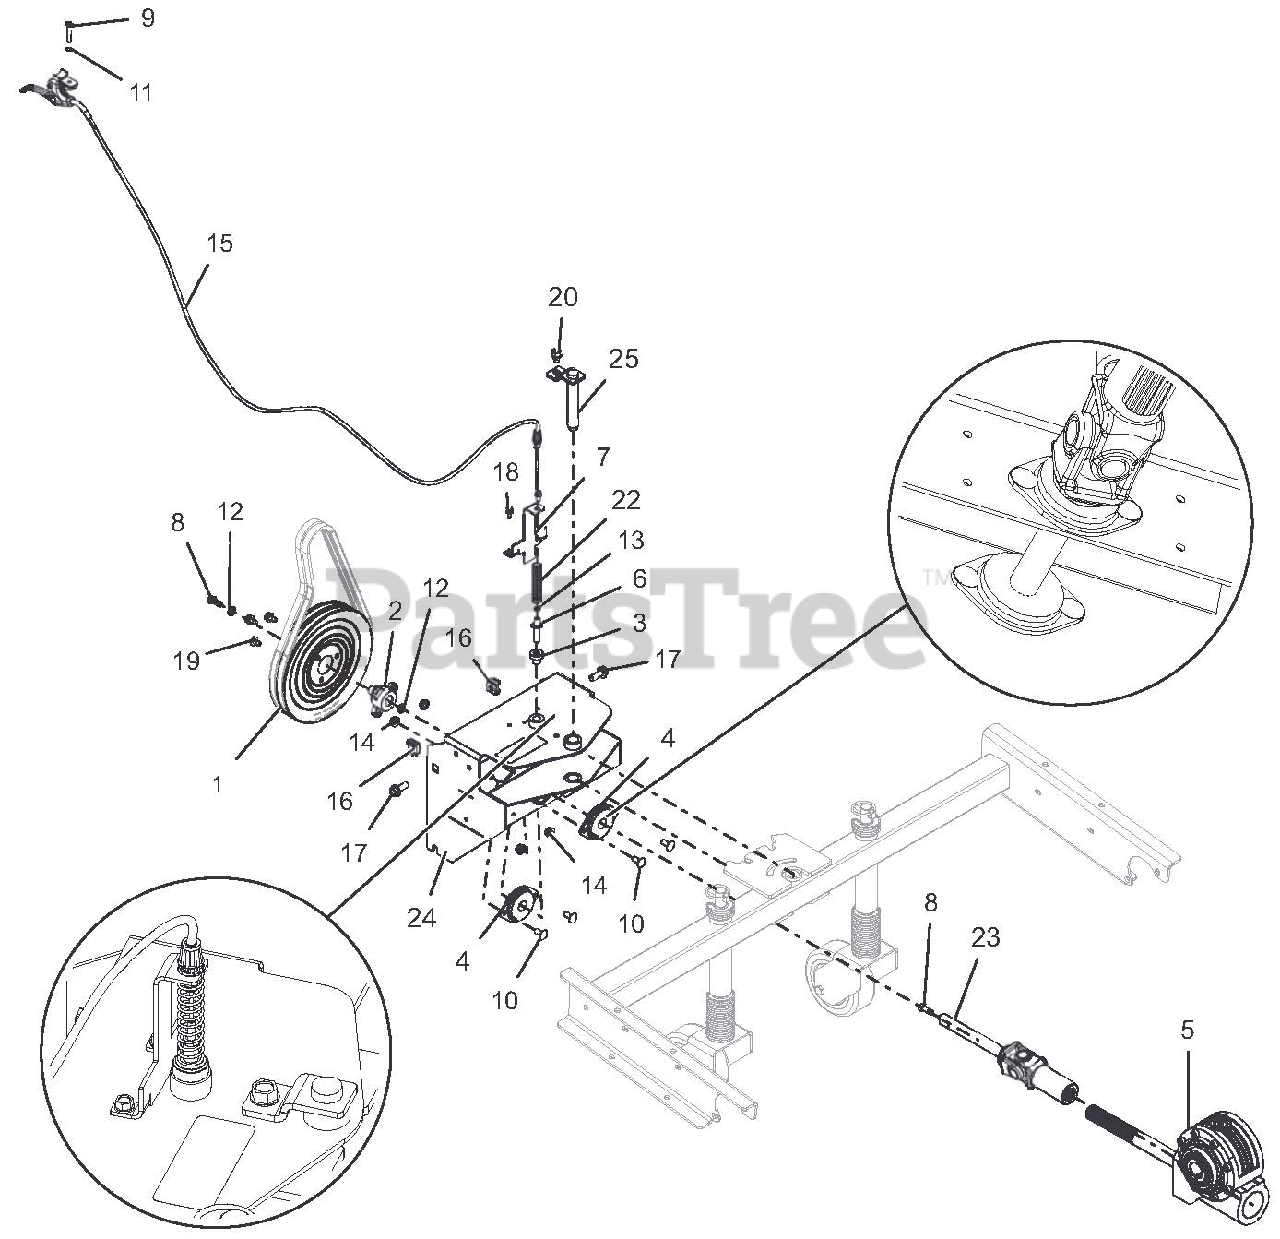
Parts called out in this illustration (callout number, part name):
1	PULLEY, DUAL GROOVE
2	HUB, ATTACHMENT PULLEY
3	SPCR, -FLANGED .390X.500X.781
4	BEARING, 2 BOLT FLANGE - .75 ID
5	GEARBOX, WORM - 8.25:1
6	PIN, ADJUSTABLE ANGLE BRUSH
7	BRKT, PIN HOLDER
8	BLT-HEX .31-24X.75 GR5 YWZC
9	SCR, -- MCH .25-20X1.50 OVAL HD
10	BLT-RDHDSQNK .31-18X.75 G5 YWZC
11	WSHR, LK-INT .250 TH TYA
12	WSHR-LK .31X.097 HVY YWZC
13	NUT-HEX 10-24 YWZC
14	NUT, LK-TOP-FLG .312-18 YWZC
15	CABLE, REMOTE BRUSH LOCK
16	NUT-RETAINER .38-16
17	BLT-SERHFWH .38-16X1.00 YWZC
18	SCR-TAP .25-20X.50 HWH TR YWZ
19	SCR-TAP .31-18X.50 HWH TR YWZ
20	SCR-TAP .38-16X.50 HWH TR YWZ
22	SPRG, COMPRESSION
23	DRIVELINE, SERIES 07 (U-JOINT)
24	ADAPTOR, 36" BRUSH, 926 FRAME (BLACK)
25	WLDMT, BRUSH PIVOT PIN
